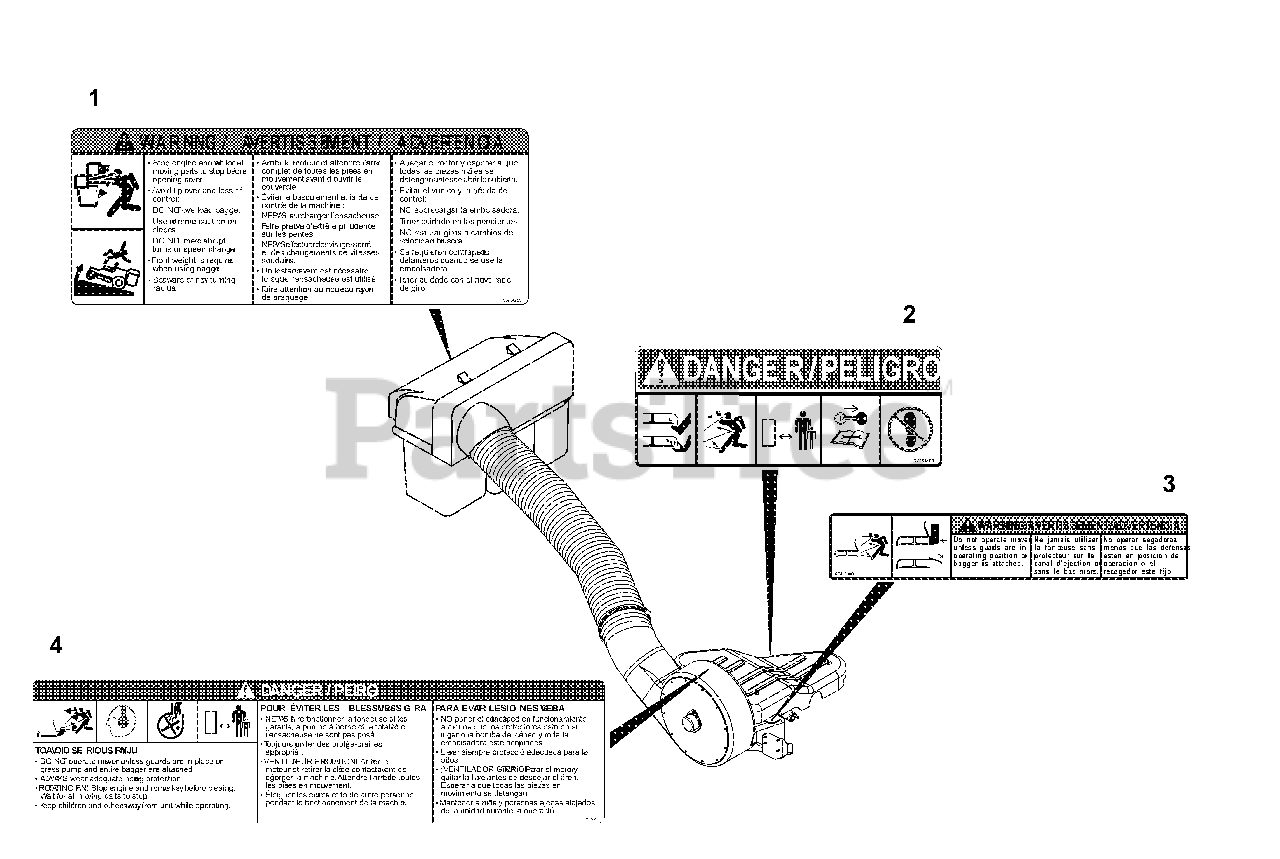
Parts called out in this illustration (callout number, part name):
1	Decal-Warning, Bagger Cover
2	Decal, Mower Pan Head Danger
3	Decal, Warning
4	Decal-Caution, Grass Pump
